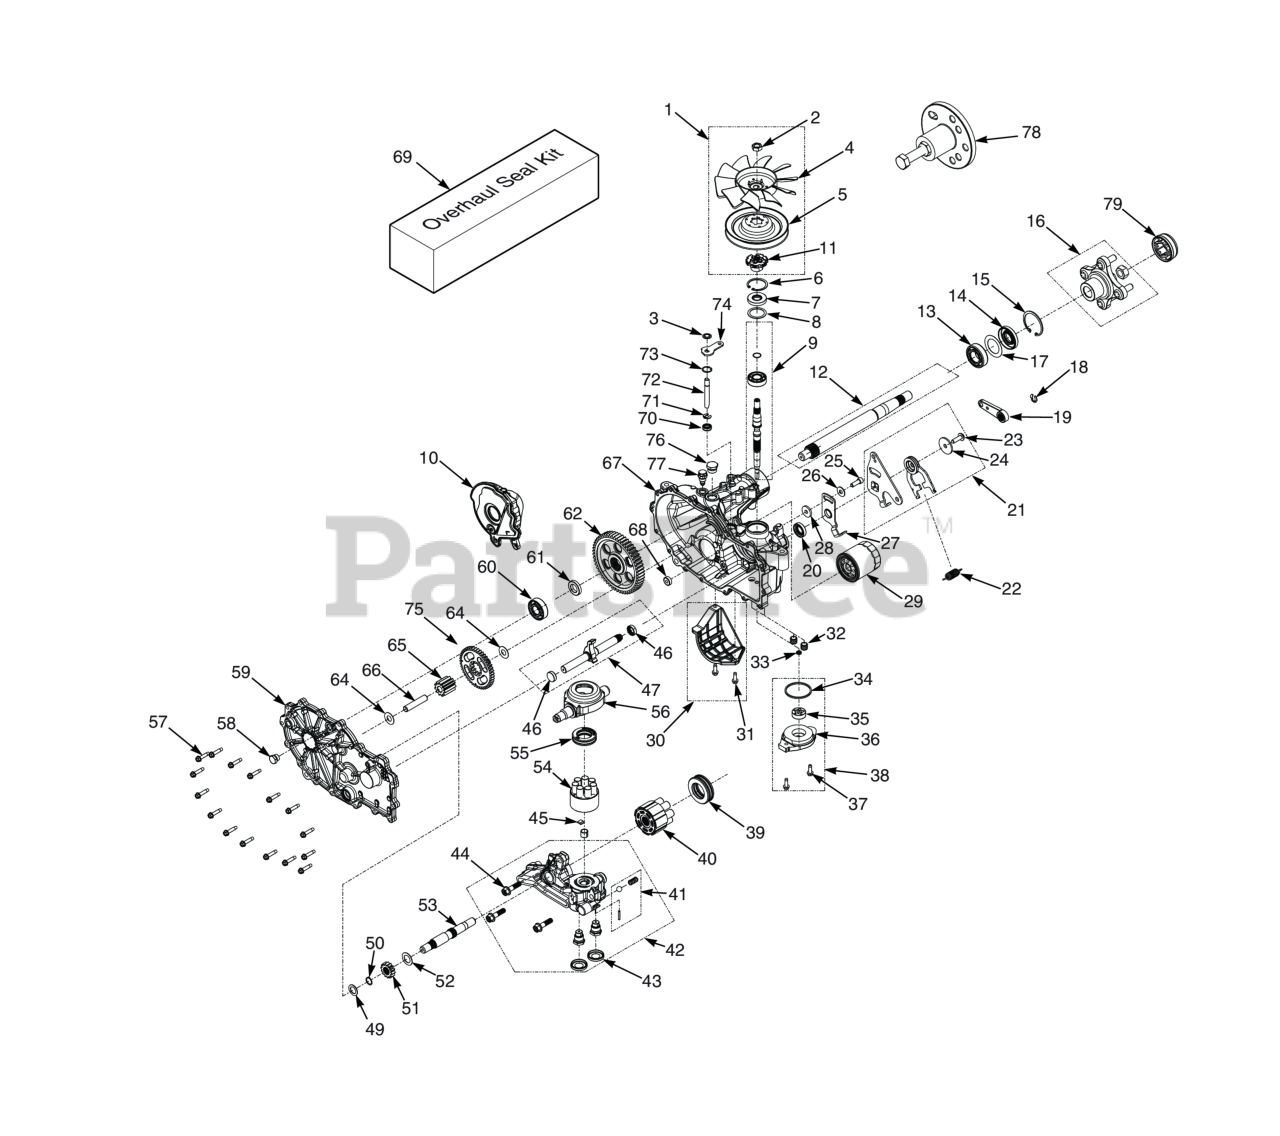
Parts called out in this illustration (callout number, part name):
1	Kit, Fan & Pulley
2	Fan Nut (order through Hydro-Gear)
3	Ring, Retainging .375 External
4	Fan, 7" (10 Blade)
5	Pulley"
6	R i n g , Retaining 2.06 Internal
7	Seal, Lip 17 x 40 x 7
8	Washer, 1.23 x 1.56 x .04
9	Kit, Input Shaft
10	Expansion Tank, Internal RH
11	Spring, Block
12	Shaft, Axle
13	Bearing, Ball 1.0 x 52 x 15 Open
14	Seal, Lip TC4 1.0 x 2.06 x .38
15	R i n g , Retaining 2.06 Internal
16	Hub, 4-Bolt
17	Washer, 1.355 x 2.035 x .021 Flat
18	Ring, Retaining External .375"
19	Handle, Brake
20	Seal, Lip 18 x 32 x 7
21	Kit, RTN Bi-Directional (Left Side)
22	Spring, Extension
23	Bolt, Hex Head Cap Screw 5/16-24 x 1" Patch
24	Washer, .343 x 1.5 x .062
25	Bolt, Hex Head Cap Screw 5/16-24 x 1" Patch
26	Washer, 7/16 x 7/8 OD x .06 HT
27	Arm, Neutral (Right Side)
28	Spacer, .32 ID x 1.005 OD x .1495 Thk
29	Filter, Oil
30	Kit, Filter Guard (RH)
31	Screw, Hex Flange 1/4-20 x .625
32	Tibe, Connecting
33	Kit, Gerotor Seal
34	Tube, Charge Triple O-ring
35	Gerotor Assembly (1.9 cc)
36	Cover, Charge Pump
37	Screw, Hex Flange 1/4-20 x .625
38	Kit, Charge Pump
39	Thrust Ball Bearing Assembly
40	Kit, 16cc Cylinder Block Assembly (steam
41	Kit, Charge Relief
42	Kit, Center Section (Right Side)
43	Seal, Plug 1.250 x .250
44	Screw, Hex Flange Head 3/8-16 x 1-1/2"
45	Plate, By-Pass
46	O-Ring, -111 x .103 x 424
47	Kit, Outboard, RH Rot B / LH Rot A (LH)
48	Pawl, Brake
49	Washer, HT .62 ID x 1.0 OD x .05 Thick
50	Ring, Retaining .625
51	Gear, 14T Steel
52	Washer, .72 x 1.16 x .04
53	Shaft, Motor
54	Assembly, Block 7 Piston
55	Bearing, Thrust
56	Trunnion, Swashplate
57	Bolt, Hex Head 1/4-20 x 1-1/8"
58	Plug, External Hex Vent 9/16-18
59	Kit, Cover (Right Side)
60	Kit, Bearing
61	Spacer, .750 x 1.320 x .257
62	Gear, 54T
63	Gear, 45T
64	Washer, .5 x 1.0 x .03
65	Gear, 11T Steel
66	Jackshaft Pin
67	Kit, Housing Main (Right Side)
68	Magnet, Ring
69	Seal Kit
70	Seal, Lip, .375 x .75 x .25
71	Ring, .Retaining .375 External
72	Rod, By-Pass
73	R i n g , Retaining .750 Internal
74	Arm, By-Pass
75	Gear, 45T
76	Plug, 3/4-16
77	Fitting 9 /16 - 18, Breather
78	Kit, Hub Puller
79	Cap, Axle
